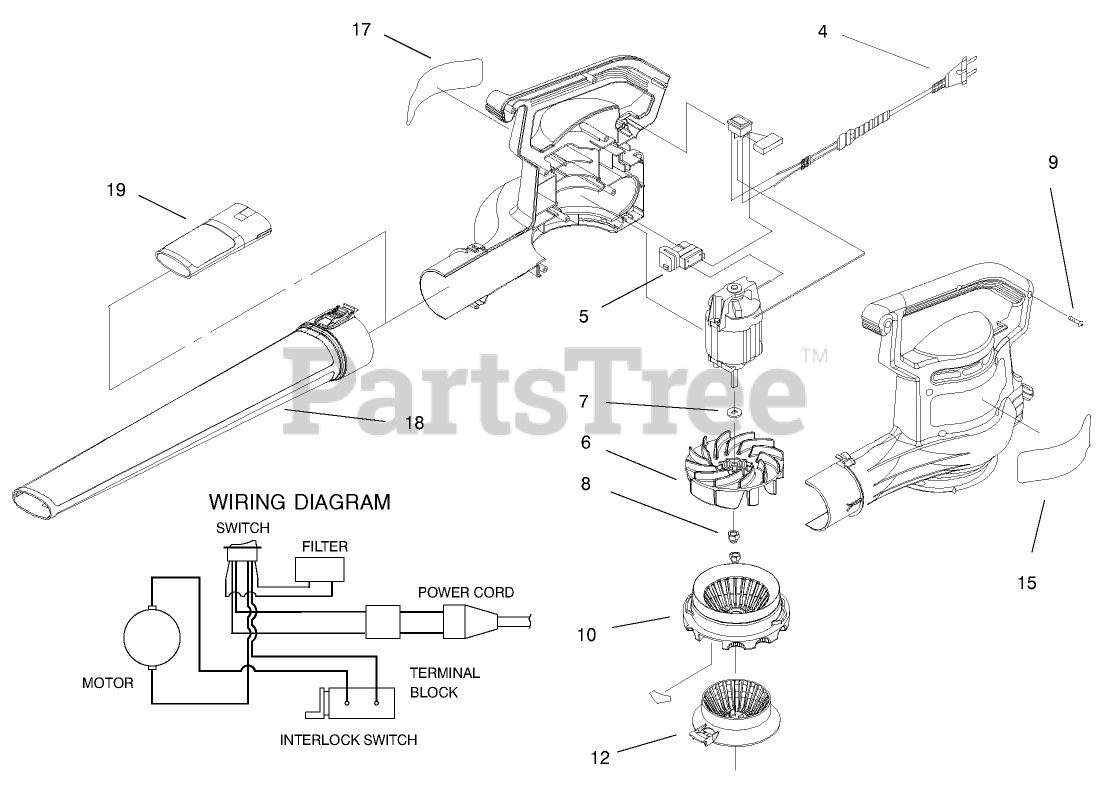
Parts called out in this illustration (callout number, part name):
4	HARNESS - BLOWER, 230 VOLT (AUSTRALIA)
5	SWITCH - INTERLOCK
6	IMPELLER - BLOWER
7	WASHER
8	NUT - IMPELLER
9	SCREW-PPH
10	ASM-INLET COVER & DECAL
12	CHOKE - AIR, RED
15	DECAL, LOGO, SUPRBLWR
17	Label Stock-Serial, Australia
18	TUBE-BLOWER LONG
19	INSERT - TUBE
